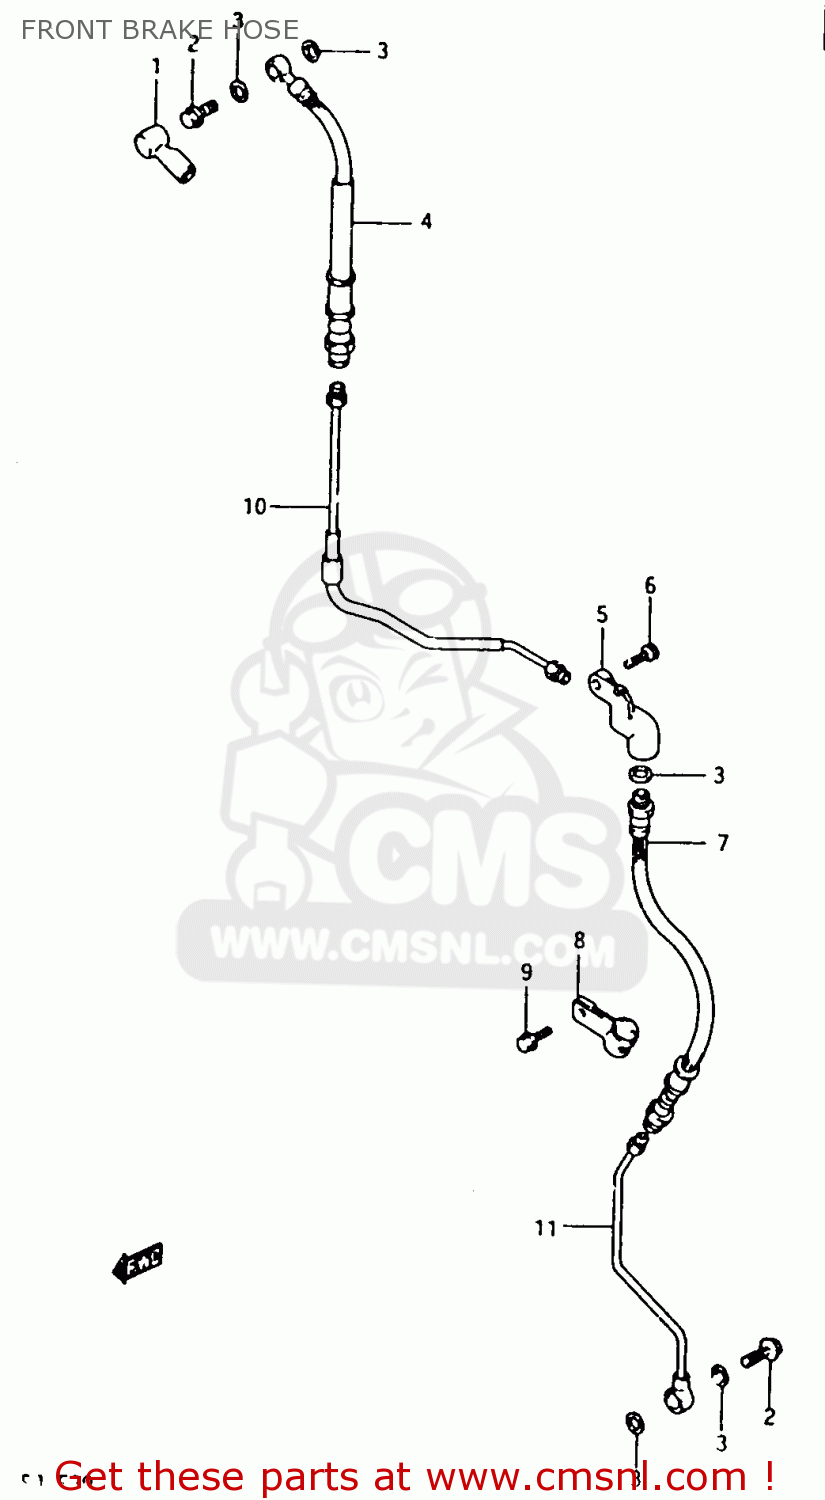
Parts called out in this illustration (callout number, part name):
1	BOOT,MASTER CYLINDER
2	BOLT,UNION
3	WASHER(10X15X1.5)
4	HOSE,FRONT BRAKE NO.1
5	JOINT,FRONT BRAKE
6	BOLT
7	HOSE,FR BRAKE NO.2
8	CLAMP,FRONT BRAKE HOSE
9	BOLT
10	PIPE,FRONT BRAKE NO.1
11	PIPE,FRONT BRAKE NO.2
